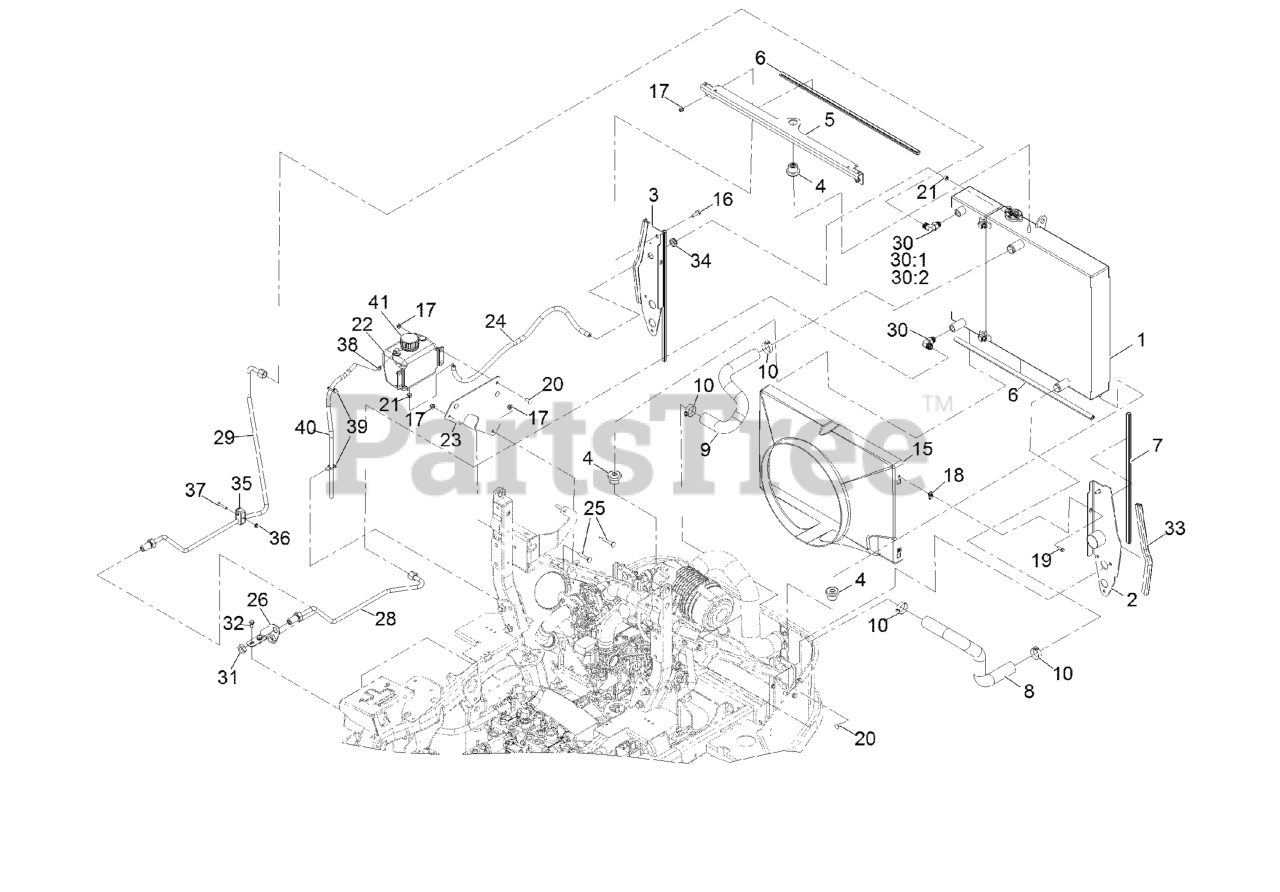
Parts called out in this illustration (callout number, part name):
1	COOLING ASM
2	SUPPORT-RADIATOR, LH
3	SUPPORT-RADIATOR, RH
4	MOUNT-ISOLATOR
5	BRACKET-COOLING, TOP
6	SEAL-BULB
7	SEAL-BULB
8	HOSE-RADIATOR, LOWER
9	HOSE-RADIATOR, UPPER
10	CLAMP-HOSE
15	SHROUD-FAN
16	SCREW-HHF
17	NUT-HF, NI
19	SCREW-HWH
20	SCREW-CARR
21	CLAMP-HOSE
22	TANK-OVERFLOW, W/CAP
23	BRACKET-BOTTLE
25	BOLT-CARR
26	BRACKET-BULKHEAD
28	HYDRAULIC TUBE ASM
29	HYDRAULIC TUBE ASM
30	FITTING-ELBOW, 90 DEG
30:1	O-RING
30:2	O-RING
31	NUT-BULKHEAD
32	Screw-HWH 5/16-18 X 3/4 Tf
33	SEAL-BULB
34	GROMMET
35	CLAMP-TWIN
37	SCREW-HH
38	CLAMP-HOSE
39	CLIP-TIE
40	HOSE-FUEL
41	CAP-W/TETHER
